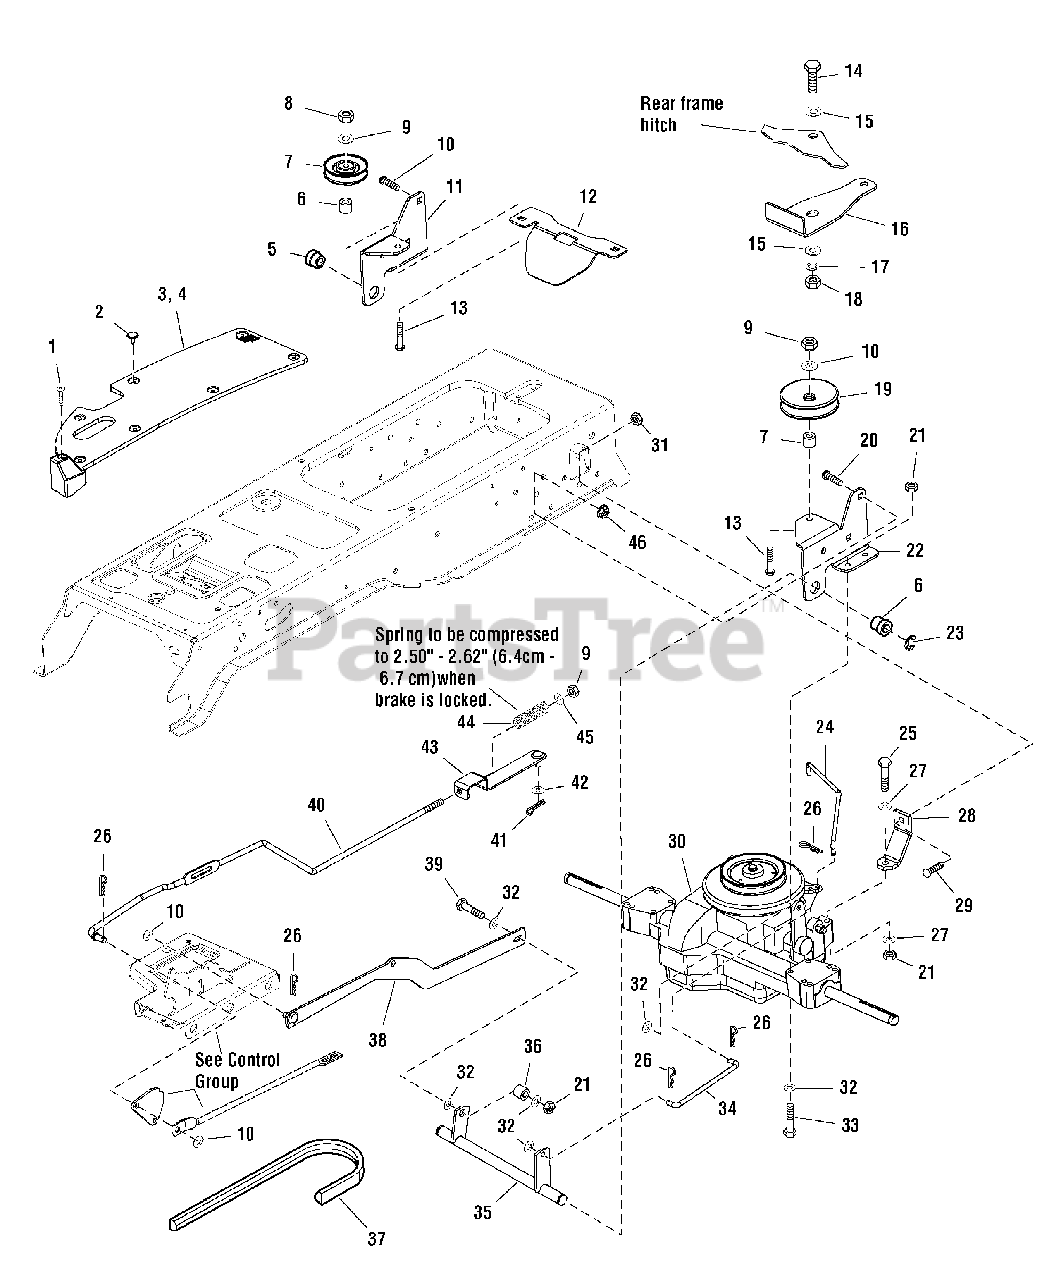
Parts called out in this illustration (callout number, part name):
1	SCREW, Pan Head Trox Taptite, 1/4-20 x 1-1/4
2	FASTENER, Panel
3	PAD, Footrest, RH
4	PAD, Footrest, LH
5	BUSHING
6	SPACER
7	PULLEY, 3" OD
8	NUT, Hex Lock ESNA, 3/8-16
9	WASHER
10	CARRIAGE BOLT, 3/8-16 x 1-1/4
11	SUPPORT, Transmission, RH
12	BRACKET, Chute
13	CARRIAGE BOLT, 3/8-16 x 2-1/4
14	CAPSCREW, Hex Head, 1/2-13 x 1-1/4
15	WASHER
16	DRAWBAR
17	LOCKWASHER, 1/2
18	NUT, Hex 1/2-13
19	PULLEY, 4" OD, Idler
20	CARRIAGE BOLT, 3/8-16 x 1
21	NUT, Hex Lock ESNA Light, 5/16-18
22	SUPPORT, Transmisson, LH
23	RING, E"
24	ROD, Free Wheel
25	CAPSCREW, Hex Head, 5/16-18 x 2
26	PIN, Quick
27	WASHER
28	STRAP, Torque
29	CARRIAGE BOLT, 5/16-18 x 3/4
30	TRANSMISSION ASSEMBLY, K46Q
31	NUT, Hex KEPS, 5/16-18
32	WASHER
33	CAPSCREW, Hex Head, 5/16-18 x 2-1/2
34	ROD
35	SHAFT ASSEMBLY
36	SPACER
37	V-BELT, Drive
38	ARM & PIN ASSEMBLY
39	CAPSCREW, Hex Head, 5/16-18 x 1
40	ROD, Brake
41	PIN, Cotter
42	WASHER
43	BRACKET & PIN ASSEMBLY
44	SPRING, Compression
45	WASHER
46	NUT, Hex KEPS, 3/8-16
